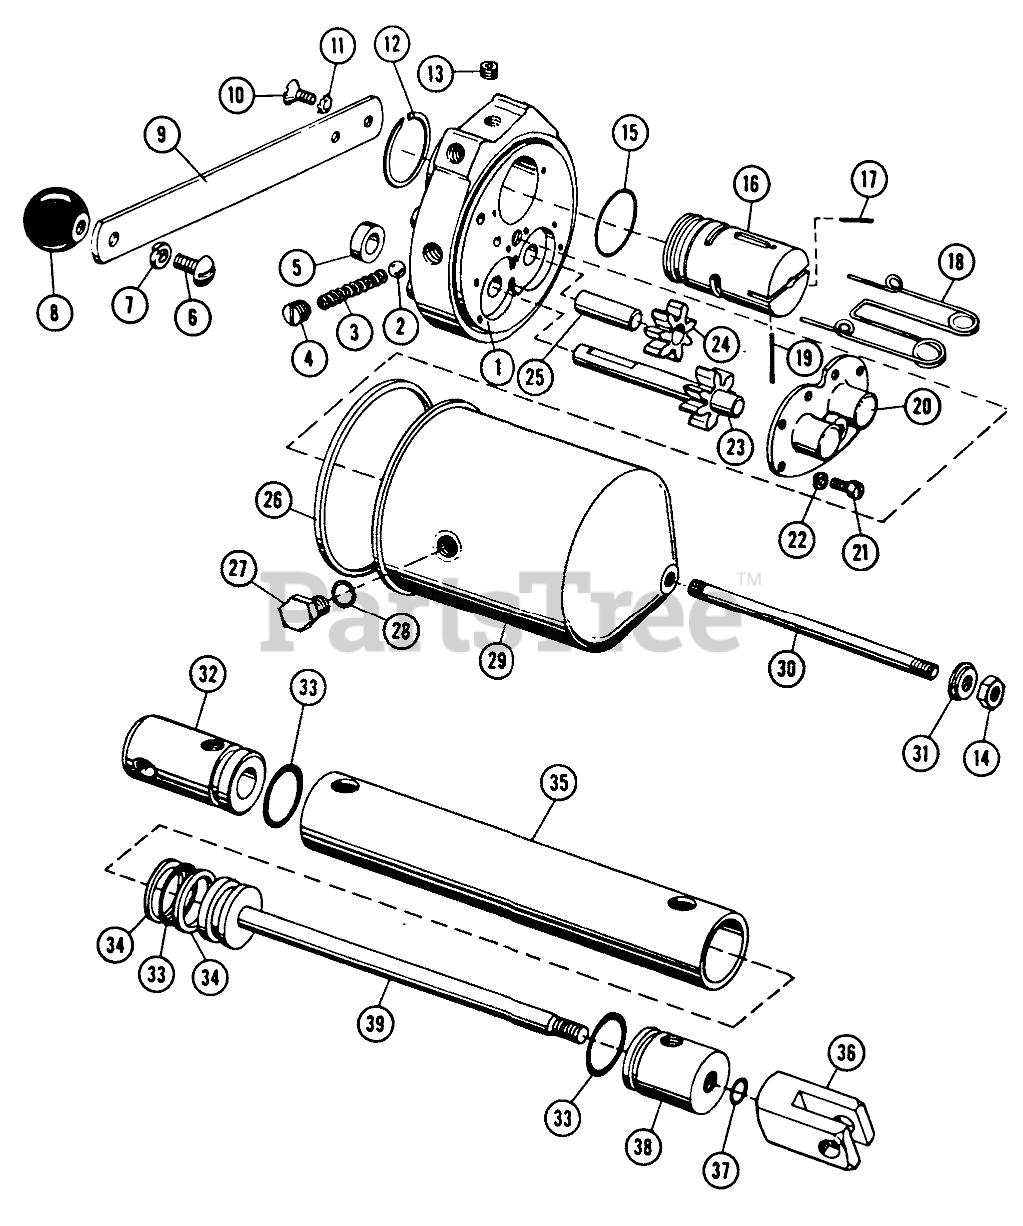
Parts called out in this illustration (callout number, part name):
1	Body
2	Ball
3	Spring
4	Plug
6	Screw 1/8-16 x 3/4
7	Lockwasher
9	Handle
10	Screw 1/4-20 x 3/8
11	Lockwasher
12	Snap Ring
13	Allen Hd. Pipe Plug
14	3/8-16 Jam Nut
15	O Ring
16	Spool Valve
17	Roll Pin 5/12 x 7/8
18	Spring
19	SPIROL PIN
20	Cover
21	Cover Screw #10-32 x 7/16
22	Lockwasher #10 External
23	Drive Shaft Ass-y.
24	Gear
25	Shaft
26	Gasket
27	Bolt-Hex 1/2-20 x 1/2
29	Reservoir
30	Stud
32	Head
34	Back Up Washer
35	Tube
36	Clevis
37	O Ring
38	Guide
39	Piston Rod Ass-y.
